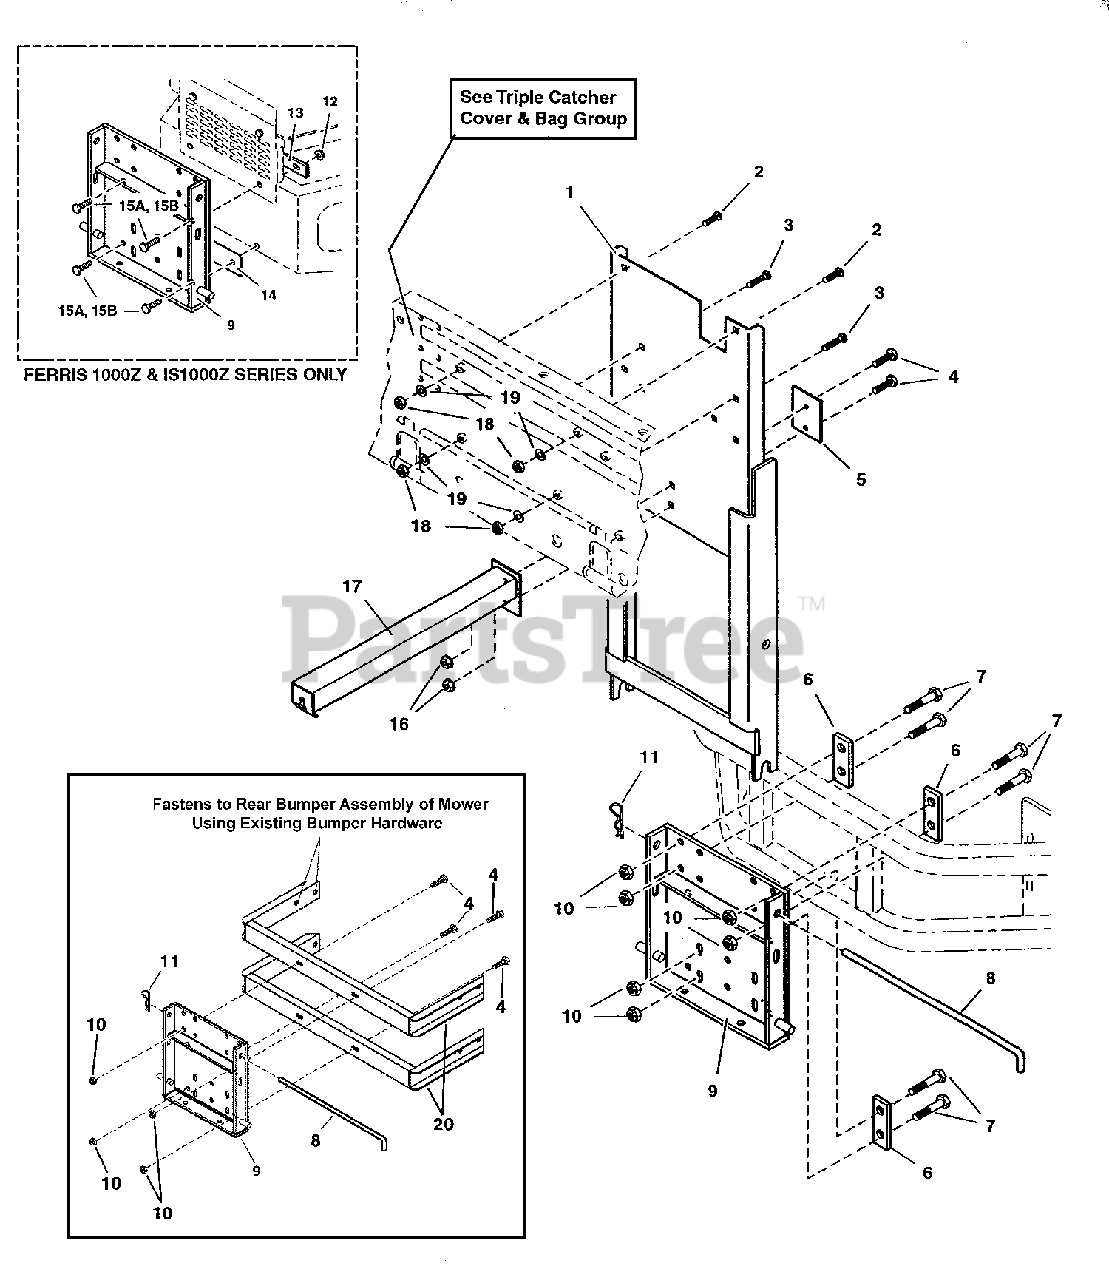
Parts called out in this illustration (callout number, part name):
1	WELDMENT, Catcher Support
2	BOLT, 5/16-18 x 3/4" Square Neck Carriage, GR5
3	BOLT, 5/16-18 x 1-1/4" Square Neck Carriage, GR5
4	SCREW, 5/16-18 x 3/4" Hex Head Cap, GR5
5	PLATE, Reinforcement
6	* BAR CLAMP
7	* SCREW, 3/8-16 x 2-1/2" Hex Head Cap, GR5
8	ROD, Hitch
9	WELDMENT, Bumper Mount Plate
10	NUT, 3/8-16 Hex Nyloc
11	* HAIRPIN, Clip
12	* NUT, 3/8-16 Hex Flange Lock
13	* REINFORCEMENT, Bumper
15A	* SCREW, 3/8-16 x 1-1/4" Hex Head Cap, GR5
15B	* SCREW, 3/8-16 x 2" Hex Head Cap, GR5
16	NUT, 5/16-18 Hex Flange Lock, GR5
17	ARM, Cover Latch (weldment)
18	NUT, 5/16-18 Hex Nyloc
19	WASHER, 5/16 Split Lock
20	STANDOFF, Bumper Mount (weldment)
